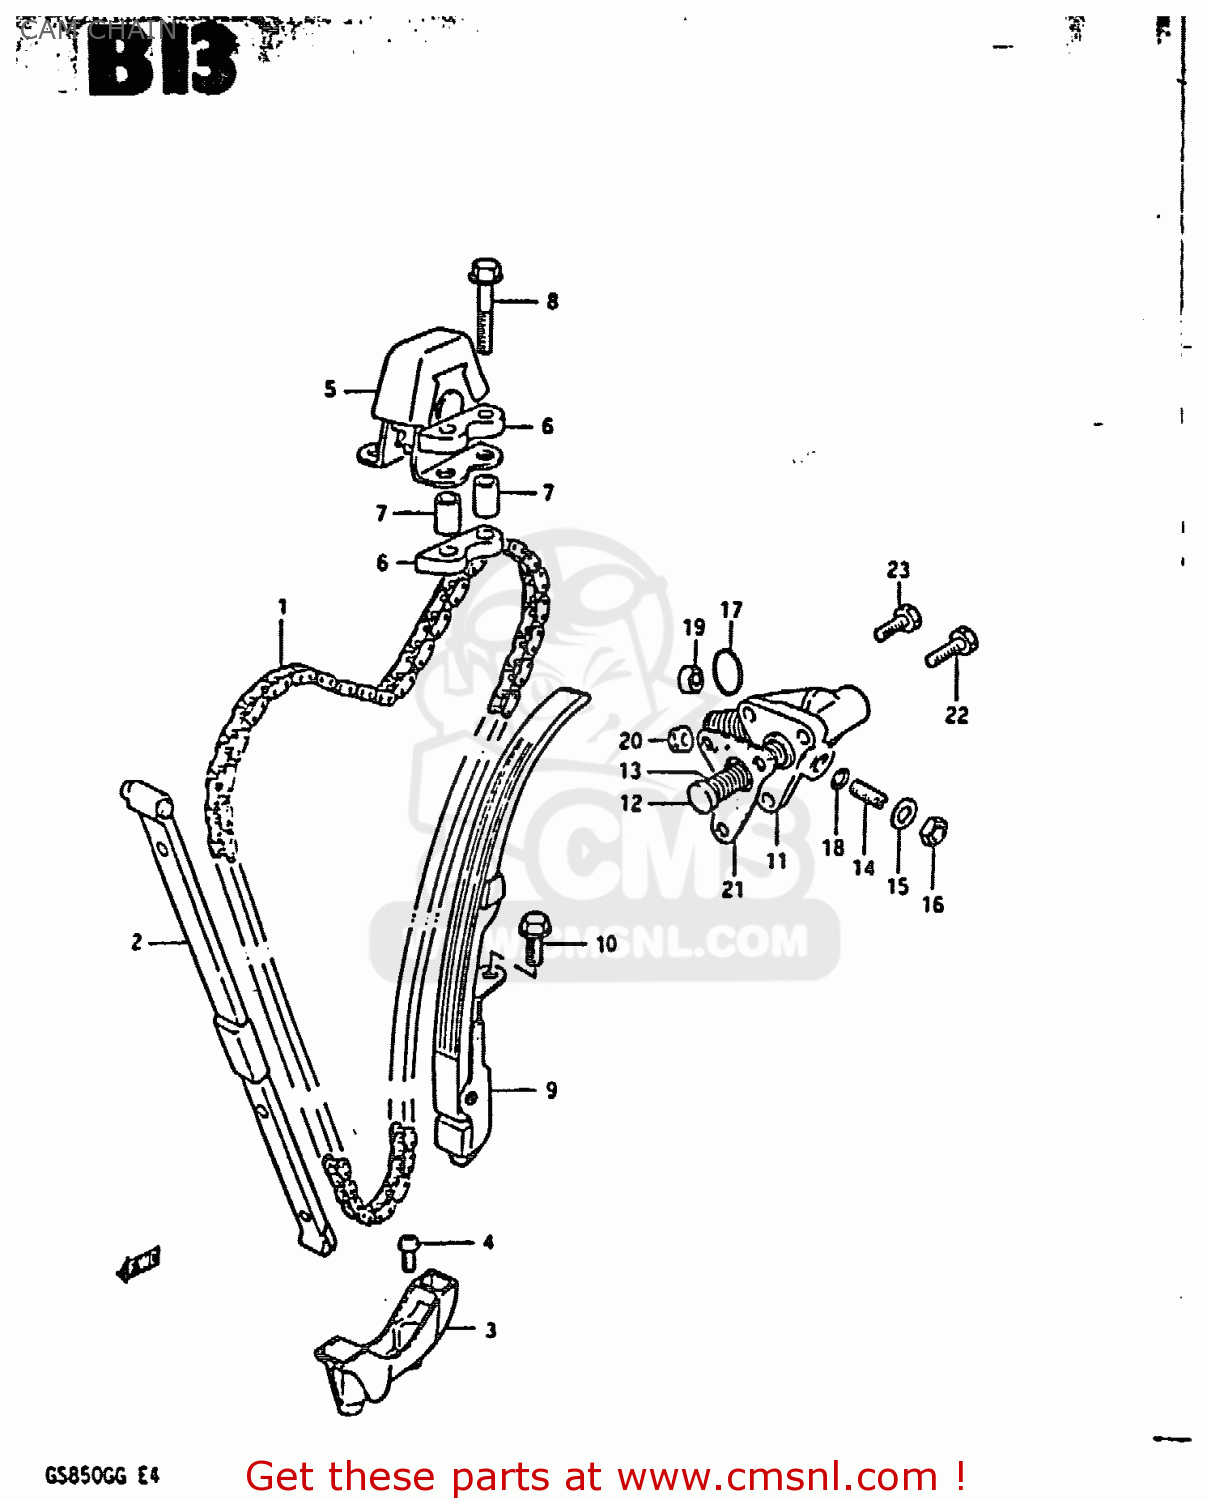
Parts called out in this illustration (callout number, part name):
1	CHAIN,CAMSHAFT DRIVE(120L)
2	GUIDE,CAM CHAIN NO.1
3	HOLDER,CAM CHAIN GUIDE
4	SCREW
5	IDLER,CAM CHAIN
6	CUSHION,IDLER
7	SPACER
8	BOLT
9	TENSIONER,CAM CHAIN
10	BOLT
11	ADJUSTER ASSEMBLY,TENSIONER
12	ROD,PUSH
13	SPRING
14	SCREW,TENSIONER ADJUST
15	WASHER
16	NUT
17	O RING(D:2.4,ID:20.8)
18	O RING(D:1.9,ID:5.7)
19	SEAL,OIL(10X16X4)
20	NUT 6MM
21	GASKET,TENSIONER ADJUSTER (MCA)
22	SCREW
23	SCREW(6X20)
